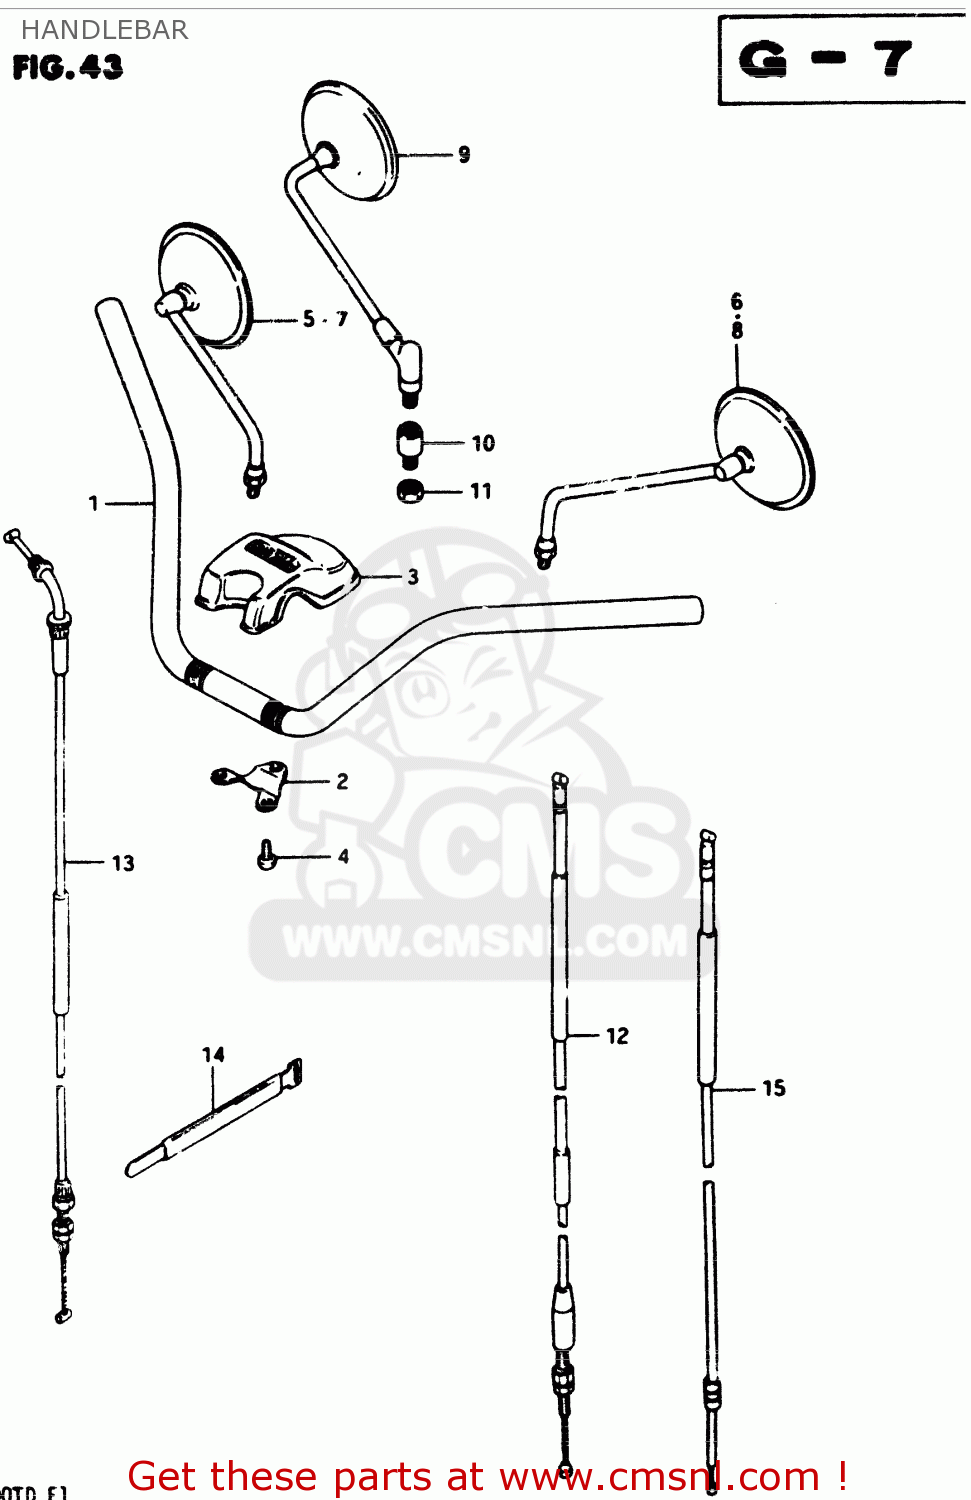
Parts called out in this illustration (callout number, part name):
1	HANDLEBAR
2	BRACKET,HEAD COVER
3	COVER,STEERING HEAD
4	SCREW
5	MIRROR ASSEMBLY,RIGHT
6	MIRROR ASSEMBLY,LEFT
7	MIRROR ASSY,RR VIEW,R
8	MIRROR, REAR VIEW LH
9	MIRROR ASSY,RH
10	CUSHION,REAR VIEW MIRROR
11	NUT
12	CABLE ASSY,CLUTCH
13	CABLE ASSEMBLY,THROTTLE
14	CLAMP
15	CABLE ASSEMBLY,STARTER
